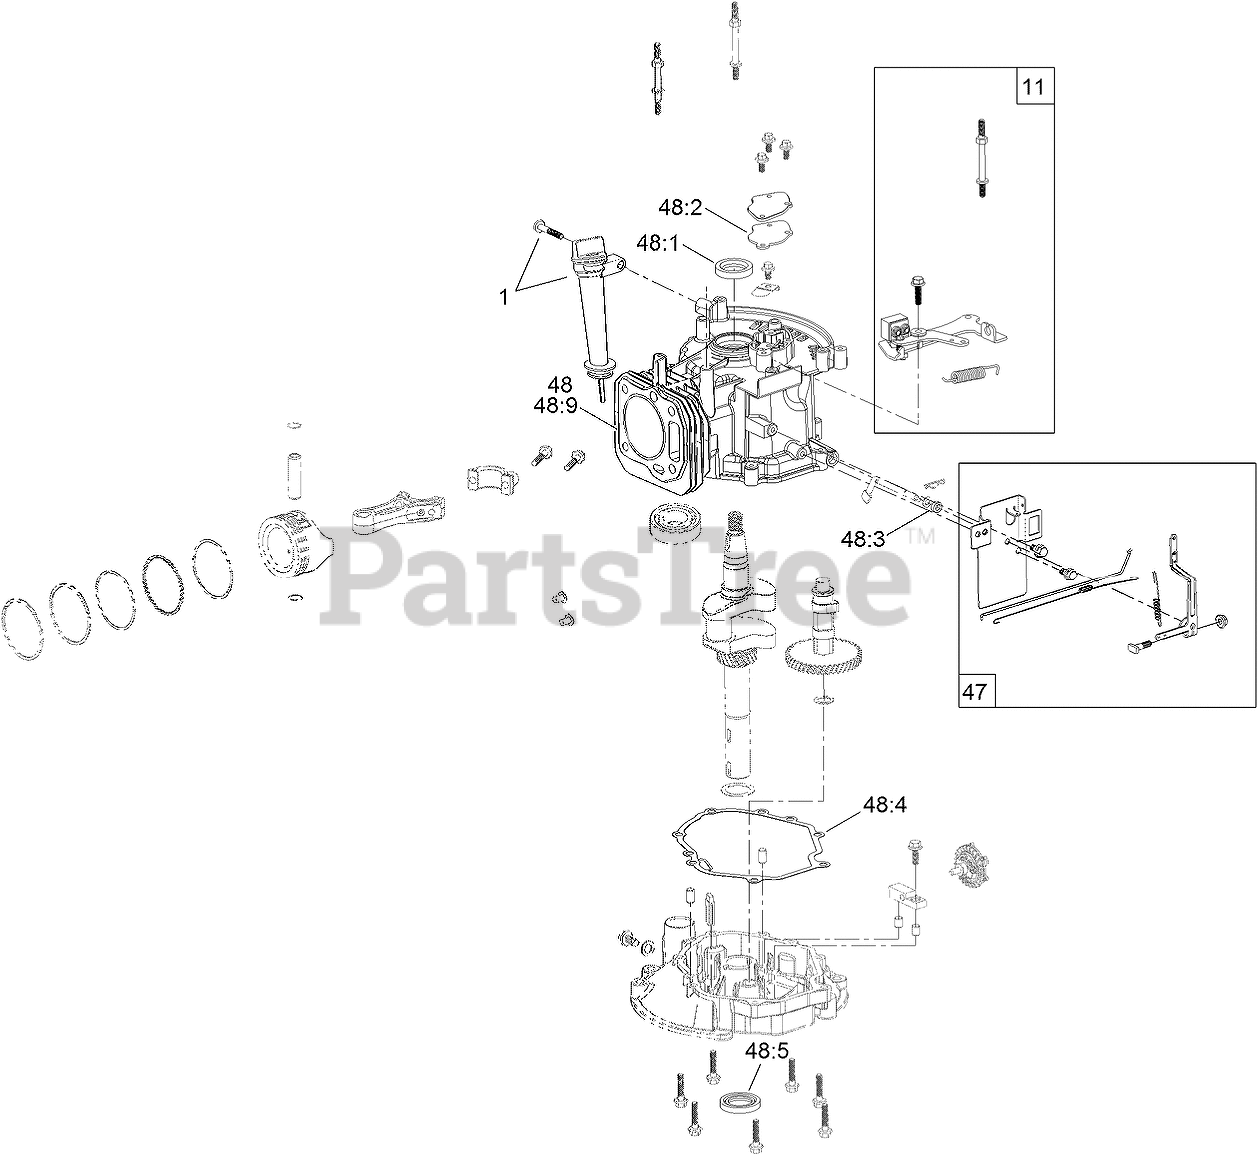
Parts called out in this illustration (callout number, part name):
1	DIPSTICK AND FILL TUBE KIT
11	BRAKE ASM RECOIL KIT
47	GOVERNOR ARM KIT
48	SEAL AND GASKET KIT
48:1	SEAL-OIL
48:2	GASKET-BREATHER
48:3	SEAL-OIL
48:4	GASKET-COVER, CASE
48:5	SEAL-OIL
48:9	GASKET-HEAD
